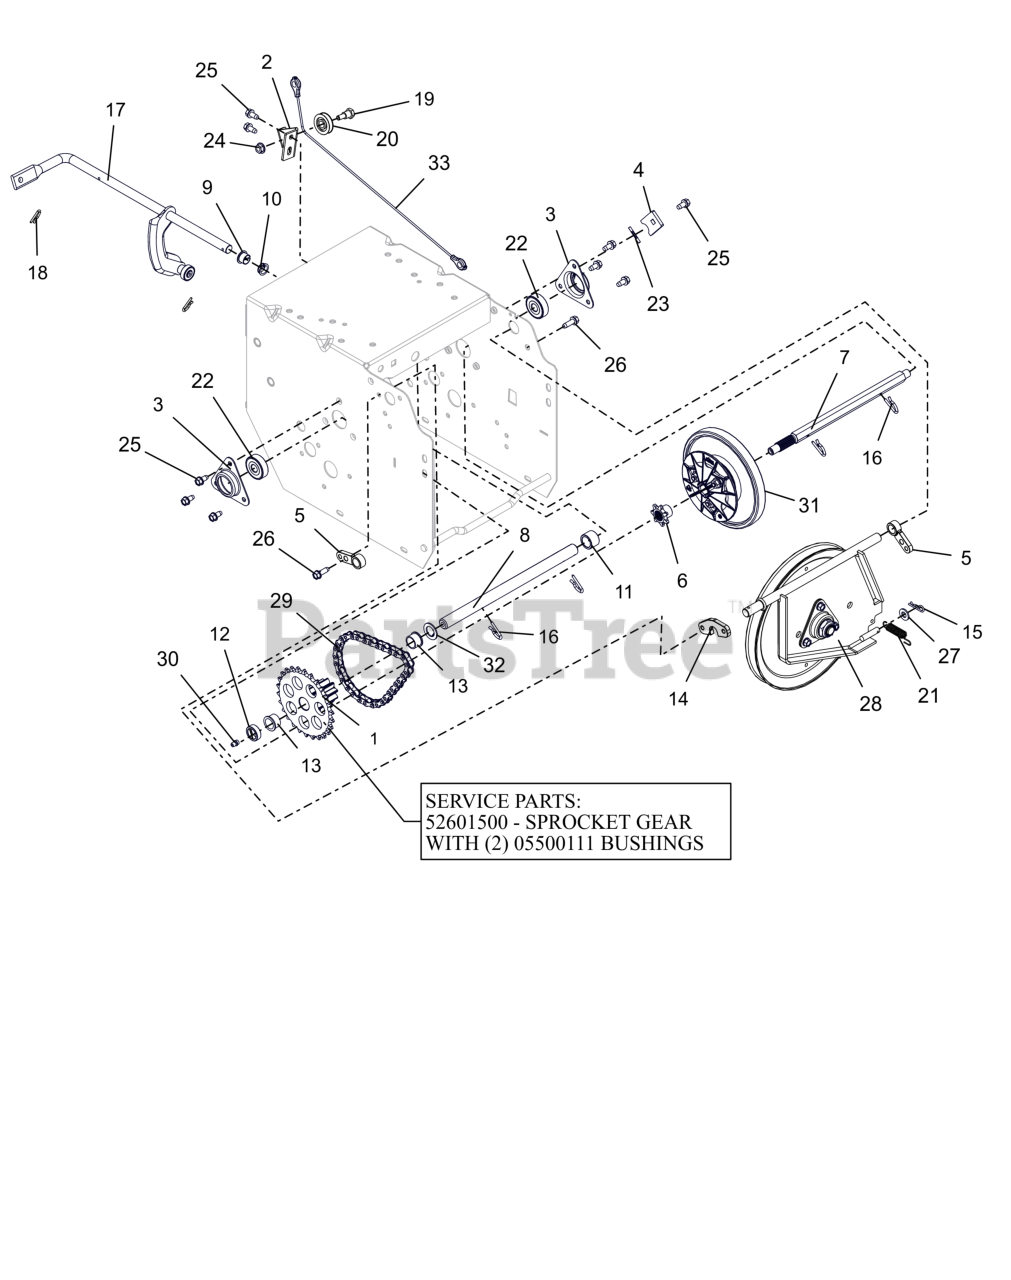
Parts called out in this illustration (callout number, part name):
1	PINION & SPROCKET
1	PINION & SPROCKET W/BUSHINGS
2	BRACKET, CABLE PULLEY
3	FLANGE, BEARING
4	TAB, ANTI ROTATION
5	SUPPORT BUSHING, SWING GATE
6	SPROCKET, PINION 7T W/SPLINE
7	SHAFT, HEX W/SPLINE TRACK
8	SHAFT, PINION TRACK
9	BUSHING, POLYLINER-.50 SPLIT
10	BUSHING, POLYLINER-.50 SNAPIN
11	SPACER, .635X.880X.611
12	BSHG-SLV, .635X.880X.305
13	BSHG-FLG .625X.750X.500X.875
14	SPACER, SWING GATE
15	PIN, HAIR #213 .08X1.19 ZCC
16	PIN, SPRING CLIP
17	ARM, SHIFT-SMALL DASH (ASSY)
18	CLIP, SPRING
19	BOLT, SHLDR -.375 X .375 X .25-20
20	PULLEY, CABLE
21	SPRING, EXT. .043X.438X1.64
22	BRG-BALL .437X1.375X.437
23	@PIN-GRV .125X1.00 TP E ALLOY
24	NUT-LK-CTR-FLG .25-20 ZC120
25	SCR-TAP .25-20X.50 HWH ZCC
26	SCR,TAP .25-20X.75 HWH TR ZCC
27	WSHR,FLT .344X.688X.065 ZCC
28	PLATE, SWING - ASSEMBLY
29	CHAIN - #41, 32 PITCHES
30	ZERK,FITTING .25X.125 DRIVE IN
31	DISC, FRICTION DRIVE-ASSEMBLY
32	WSHR, FLT .630X1.005X.062 ZCC
33	CABLE, LOWER TRACTION (CMPCT)
